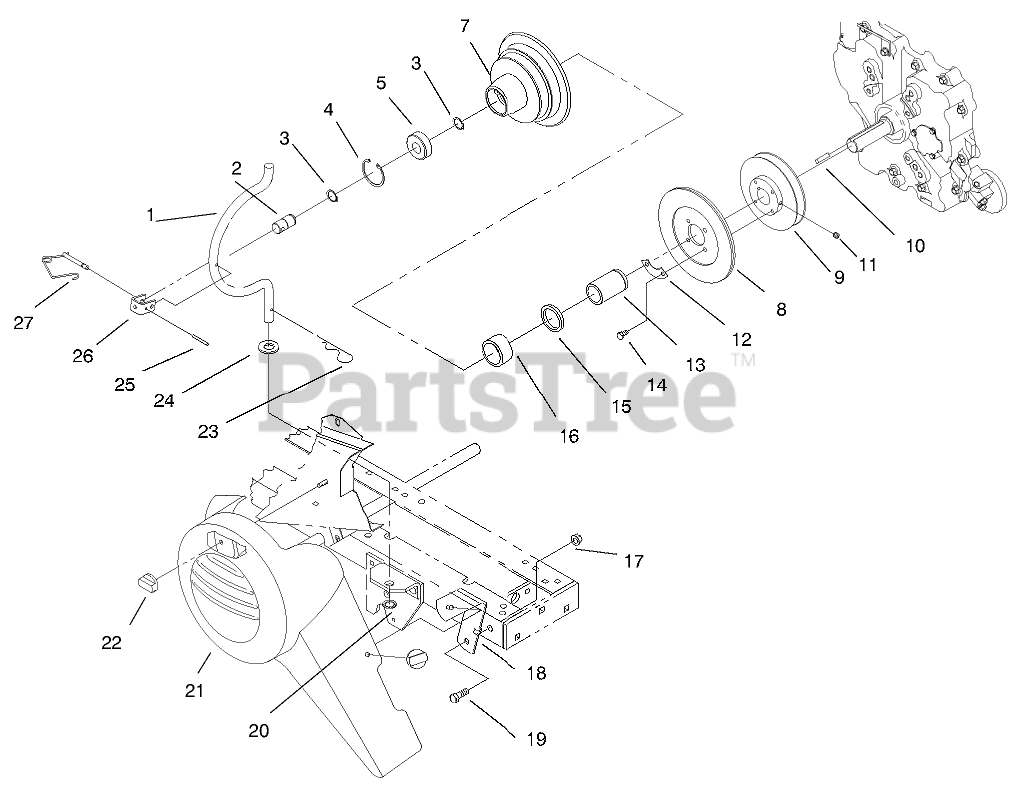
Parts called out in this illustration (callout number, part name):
1	ROD-HOUSING
2	SHAFT-PTO
3	Ring-Snap
4	RING-RETAINING
5	BEARING-BALL
7	Housing-Clutch
8	ASS'Y-CLUTCH PLATE
9	PULLEY
11	SCREW-SET, HSH
12	RETAINER
13	RACE-BEARING
14	SCREW-HEX HD CAP
15	SEAL-OIL
16	Seal
17	NUT-FLANGE
18	BELT COVER BRKT ASM
19	SCREW-HH
20	RING-REINFORCED CIRC
21	GUARD - BELT
22	NUT - WING
23	PIN-COTTER, HAIR
24	WASHER-FLAT
26	CLEVIS
27	LOCKING PIN ASM
